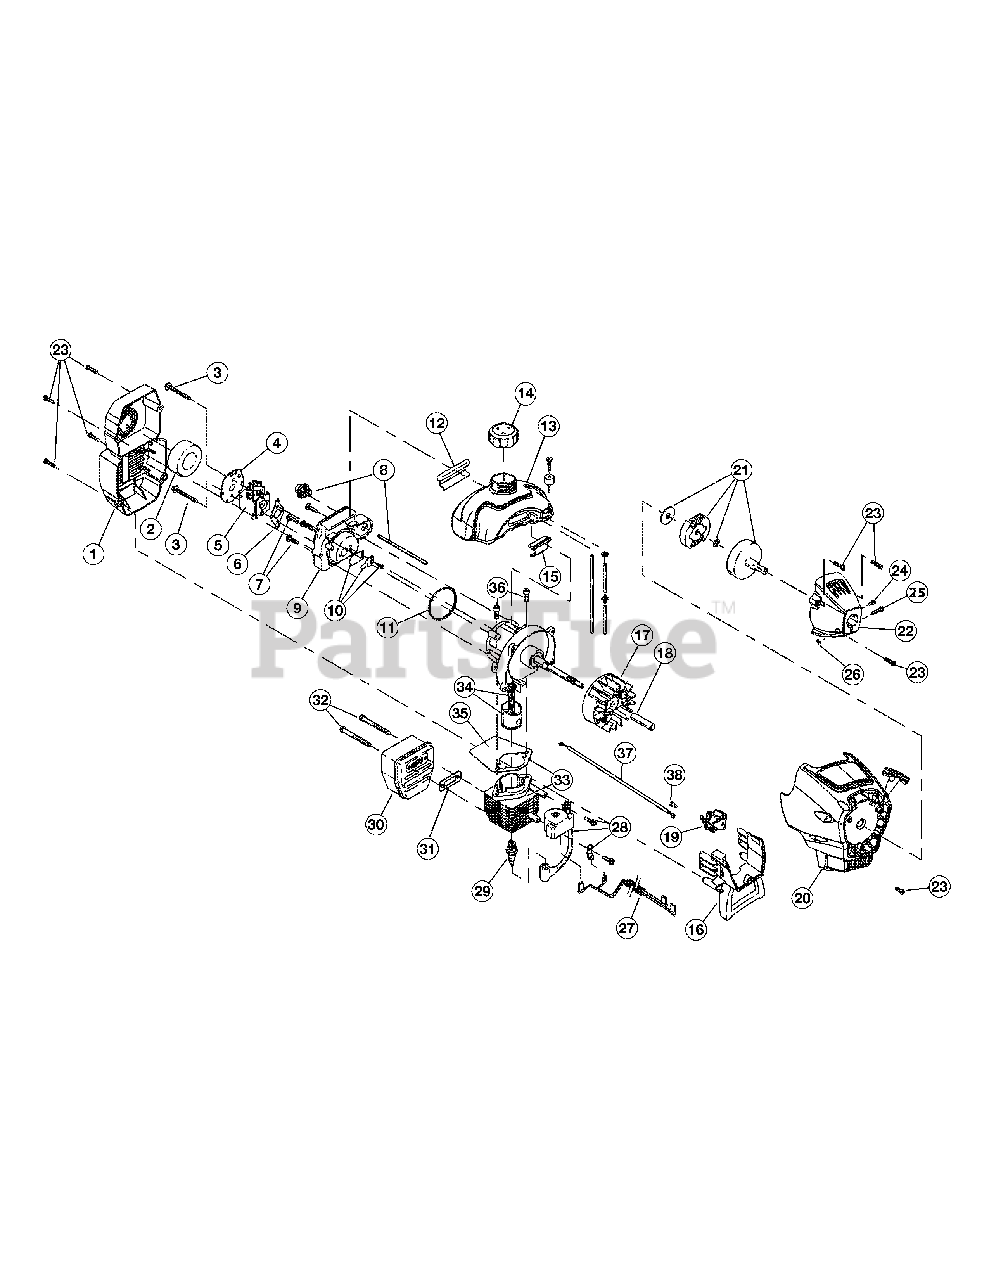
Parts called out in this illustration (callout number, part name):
1	Air Cleaner Assembly
2	Air Cleaner Filter
3	Carburetor Mounting Screw Assembly
4	Choke Plate
5	Carburetor Assembly
6	Carburetor Gasket
7	Carb Mount Screw
8	Primer and Hose Assembly
9	Carb Mount Assembly
10	Reed Assembly
11	Carburetor Mount Gasket
12	Rear Mounting Pad
13	Fuel Tank Assembly
14	Fuel Cap Assembly
15	Front Mounting Pad
16	Shroud Extension & Stand
17	Flywheel Assembly
19	ACL Lever Assembly
20	Starter Housing Assembly
21	Clutch Assembly
22	Clutch Cover Assembly
23	Cover Screw
24	Anti-Rotation Screw
25	Clamping Screw
26	Clamping Nut
27	Wire Leads
28	Module Assembly
29	Spark Plug
30	Muffler Assembly
31	Exhaust Gasket
32	Muffler Mounting Bolt Assembly
33	Cylinder Assembly
34	Piston and Rod Assembly
35	Cylinder Gasket
36	Cylinder Bolt
37	ACL Throttle Cable
38	ACL Screw
